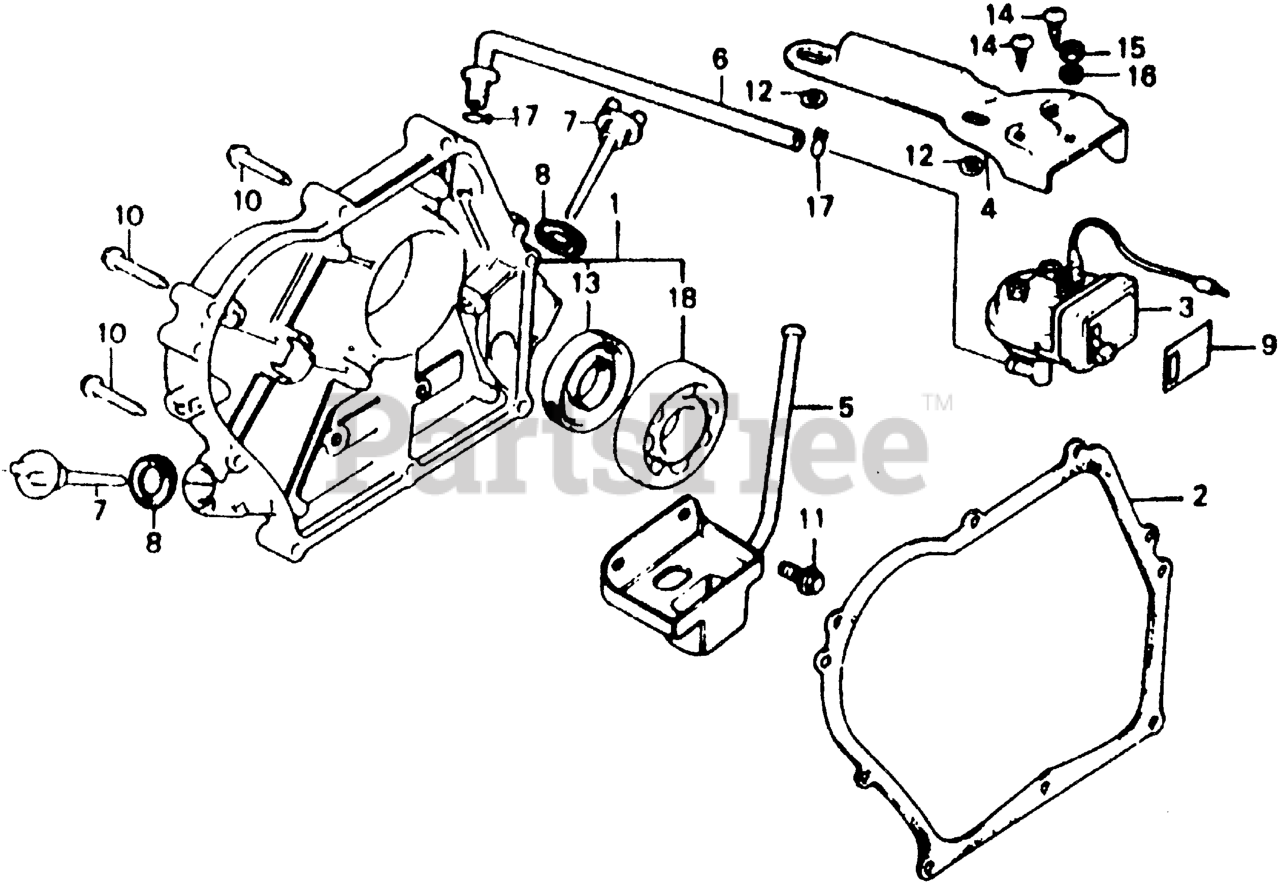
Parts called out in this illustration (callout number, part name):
1	COVER ASSY., CRANKCASE (EGZ-TYPE)
2	GASKET, COVER
3	SWITCH ASSY., UNIT
4	BRACKET, UNIT SWITCH
5	CUP, OIL
6	TUBE, OIL ALERT
7	CAP, OIL
8	GASKET, OIL FILLER CAP Use from Engine SN 1391010.
9	MARK, CAUTION (ENGLISH/FRENCH)(SPANISH)
10	BOLT, FLANGE (6X32)
11	BOLT, FLANGE (6X16)
12	WASHER (18MM)
13	OIL SEAL (25X41X6)
14	SCREW, TAPPING (5X10)
15	NUT, HEX. (5MM)
16	WASHER, SPRING (5MM)
17	CLIP, TUBE (C11)
18	BEARING, RADIAL BALL (6205)
